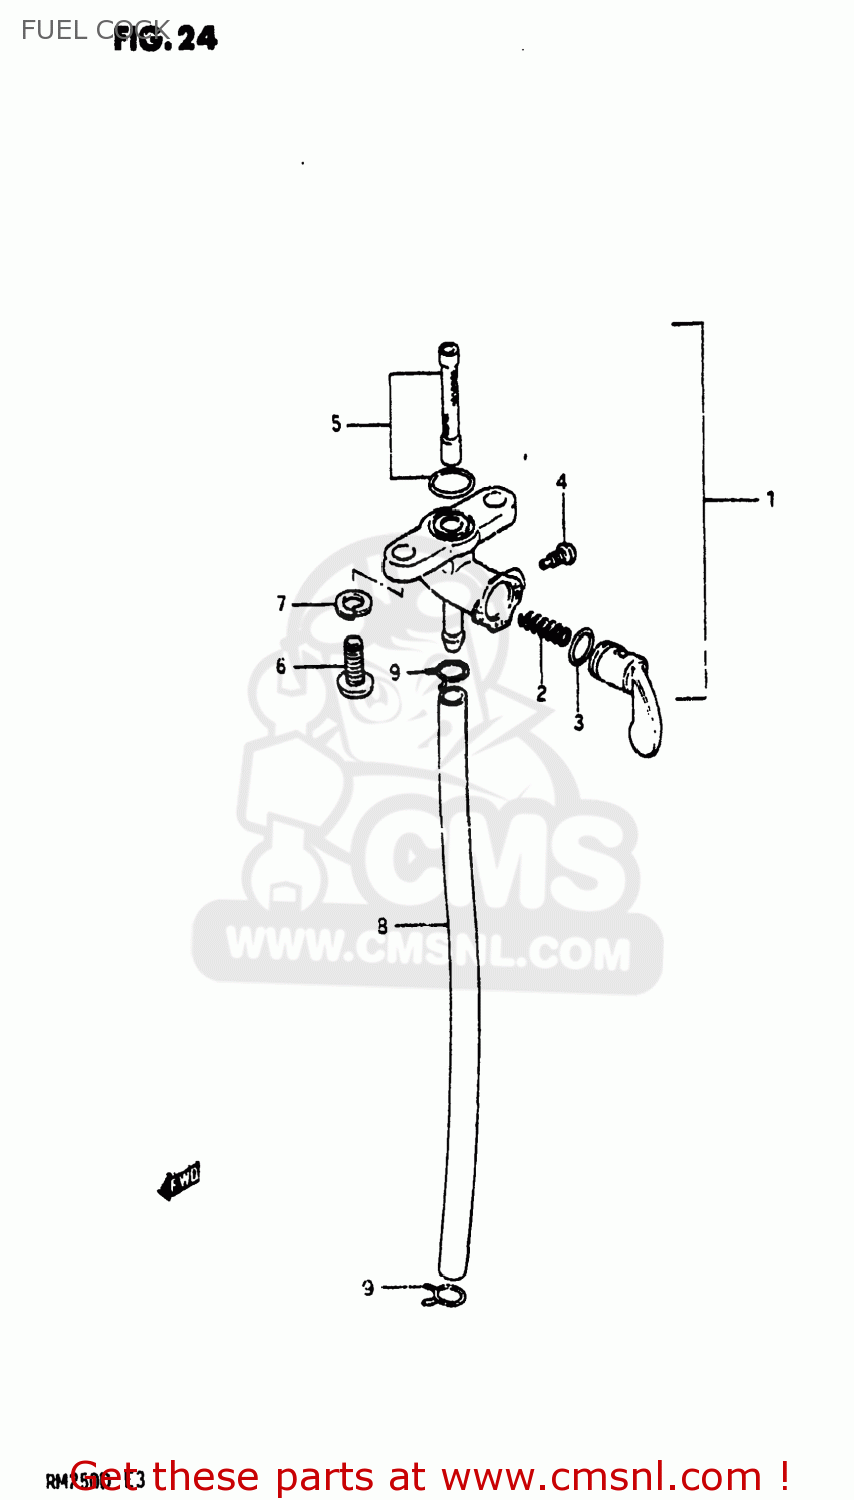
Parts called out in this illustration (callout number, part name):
1	COCK ASSEMBLY,FUEL
2	SPRING,FUEL COCK VALUE
3	O RING,LEVER
4	SCREW
5	FILTER SET FUEL
6	SCREW
7	LOCK WASHER
8	HOSE,FUEL
9	CLIP
